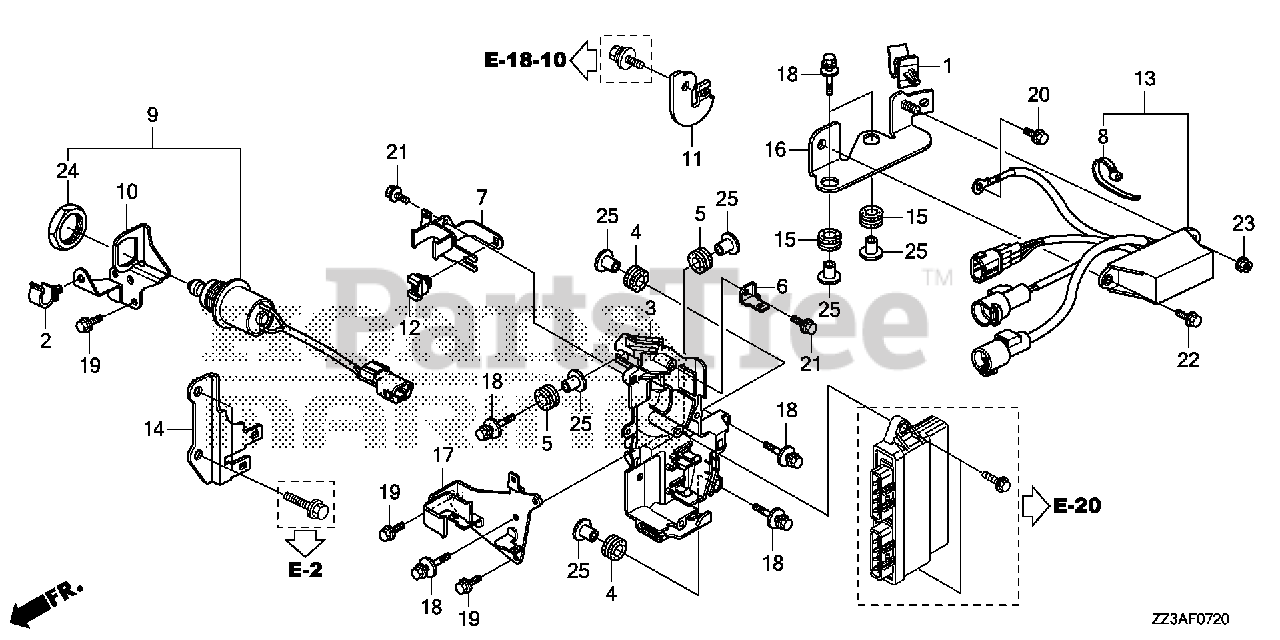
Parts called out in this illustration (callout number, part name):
1	CLAMP, FUEL TUBE
2	CLAMP B, FUEL TUBE
3	CASE, ELECTRONIC PARTS
4	GROMMET, ELECTRONIC PARTS CASE
5	GROMMET, MODULE IGNITION CONTROL CASE (CDI)(B)
6	BRACKET, ALTERNATOR FUSE
7	BRACKET, FUSE
8	TIE, CABLE (2.4X92) (NATURAL)
9	SWITCH ASSY., NEUTRAL
10	BRACKET, NEUTRAL SWITCH
11	BRACKET, POWER TILT SWITCH CONNECTOR
12	CLIP, CONNECTOR HOLDER (B)
13	RELAY ASSY., POWER TILT
14	BRACKET A, POWER TILT CONNECTOR
15	GROMMET, RELAY BRACKET
16	BRACKET, POWER TILT RELAY
17	BRACKET, MAIN RELAY
18	BOLT-WASHER (6X27) (CT200)
19	BOLT, FLANGE (6X14) (CT200)
20	BOLT, FLANGE (6X12)
21	BOLT, FLANGE (6X10)
22	BOLT, FLANGE (6X14)
23	NUT, FLANGE (6MM)
24	NUT, HEX. (20MM)
25	COLLAR, MODULE IGNITION CONTROL CASE (CDI)
